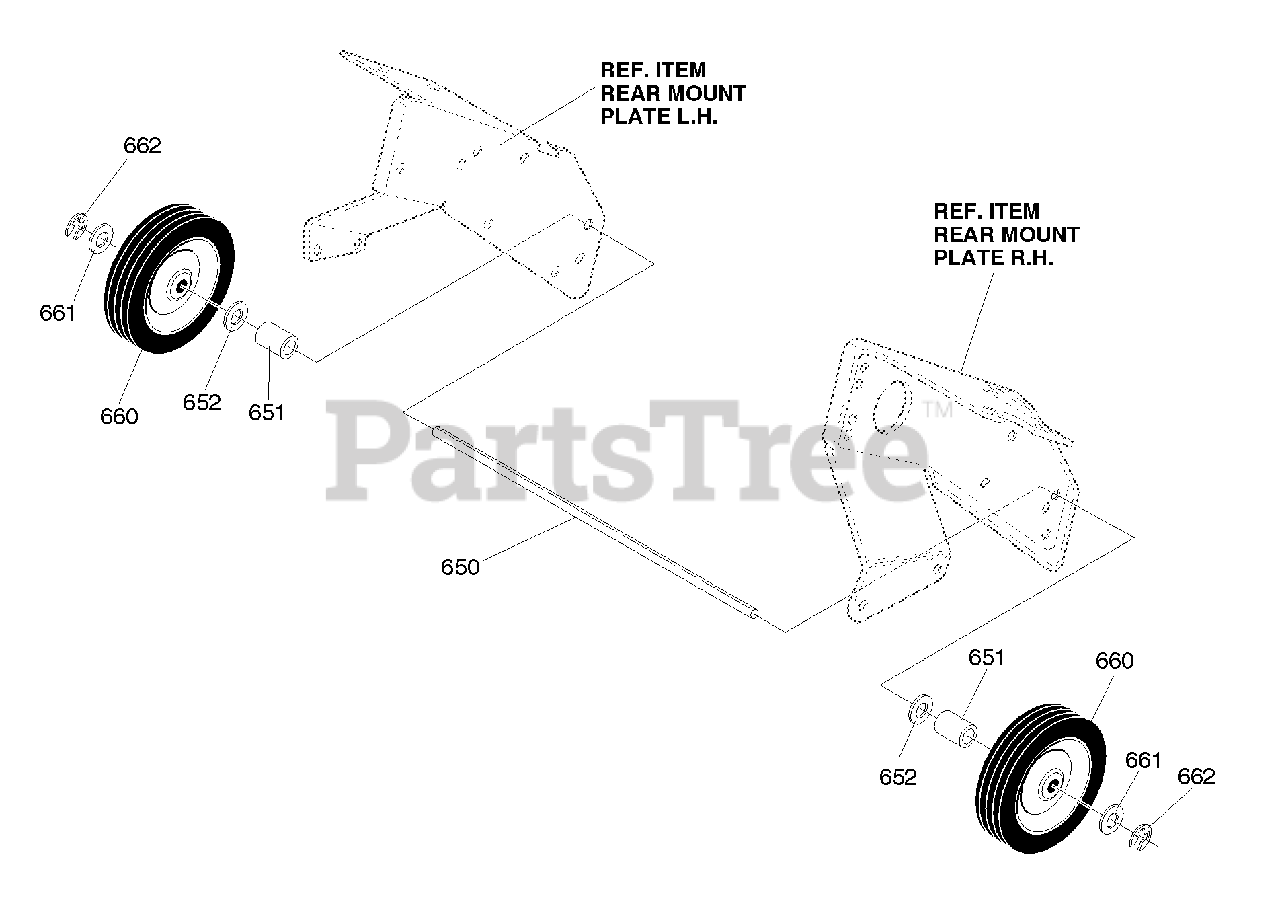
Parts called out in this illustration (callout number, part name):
650	SHAFT, AXLE 5/21 SC
651	SPACER, SLEV .407 X .63 X .440
652	FLATWASHER .406 X .81 X .065
660	TIRE & RIM 8 X 1.75
661	FLATWASHER .406 X .81 X .065
662	RING, RET E .30 X .04
